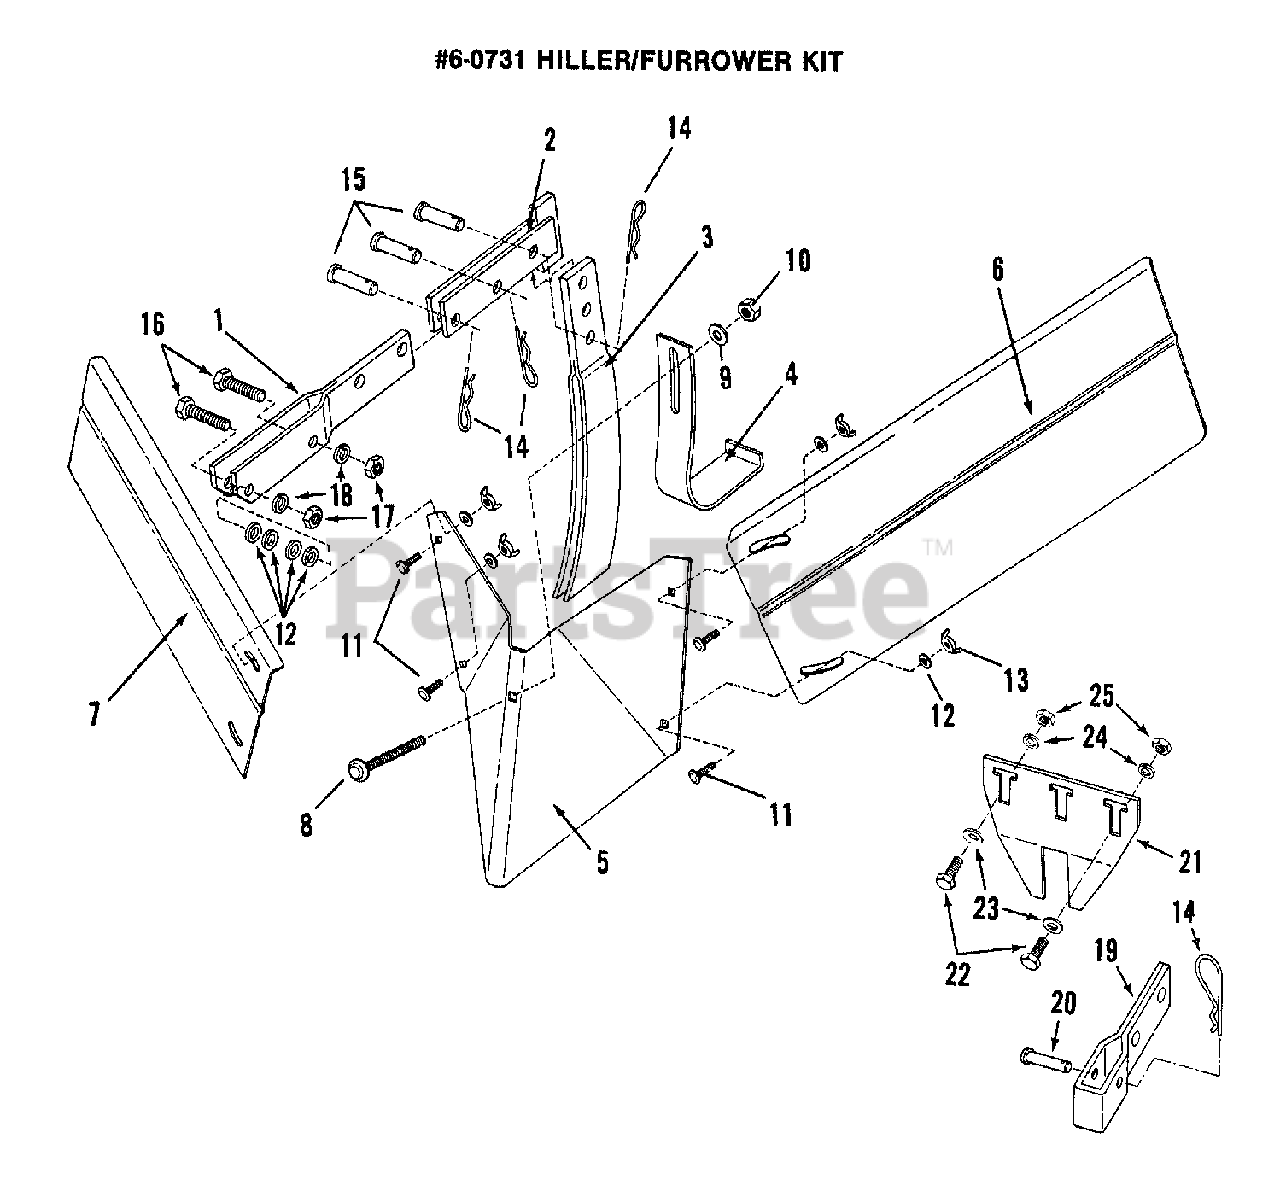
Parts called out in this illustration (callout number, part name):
1	BRACKET, Clevis
2	DRAW-BAR
3	STANDARD
4	SKID-SHOE
5	HILLER-FURROWER
6	WING, Left Side Hiller
7	WING, Right Side Hiller
8	BOLT, 1/2-13 x 3-1/2" Sh. Neck. Carriage GR2
9	WASHER, 1/2" Flat
10	NUT, 1/2-13 Hex GR5 or B
11	BOLT, 5/16-18 X 3/4" Square Neck Carriage GR5
12	WASHER, 5/16" Flat
13	WING-NUT, 5/16-18
14	PIN, 1/8" Hair
15	PIN, 1/2 x 1" Clevis
16	BOLT, 5/16-18 x 1-1/2" Hex Head Cap GR5
17	NUT, 5/16-18 Hex GR5 or B
18	WASHER, 5/16" Split Lock
19	BRACKET, Mounting (Front Tine Tiller only)
20	PIN, 3/8 x 1-1/2" Clevis (Front Tine Tiller only)
21	SUPPORT, Clevis
22	SCREW, 3/8-16 x 3/4" Hex Head Cap GR5
23	WASHER, 3/8" Flat
24	WASHER, 3/8" Split Lock
25	NUT, 3/8-16 Hex GR5 or B
